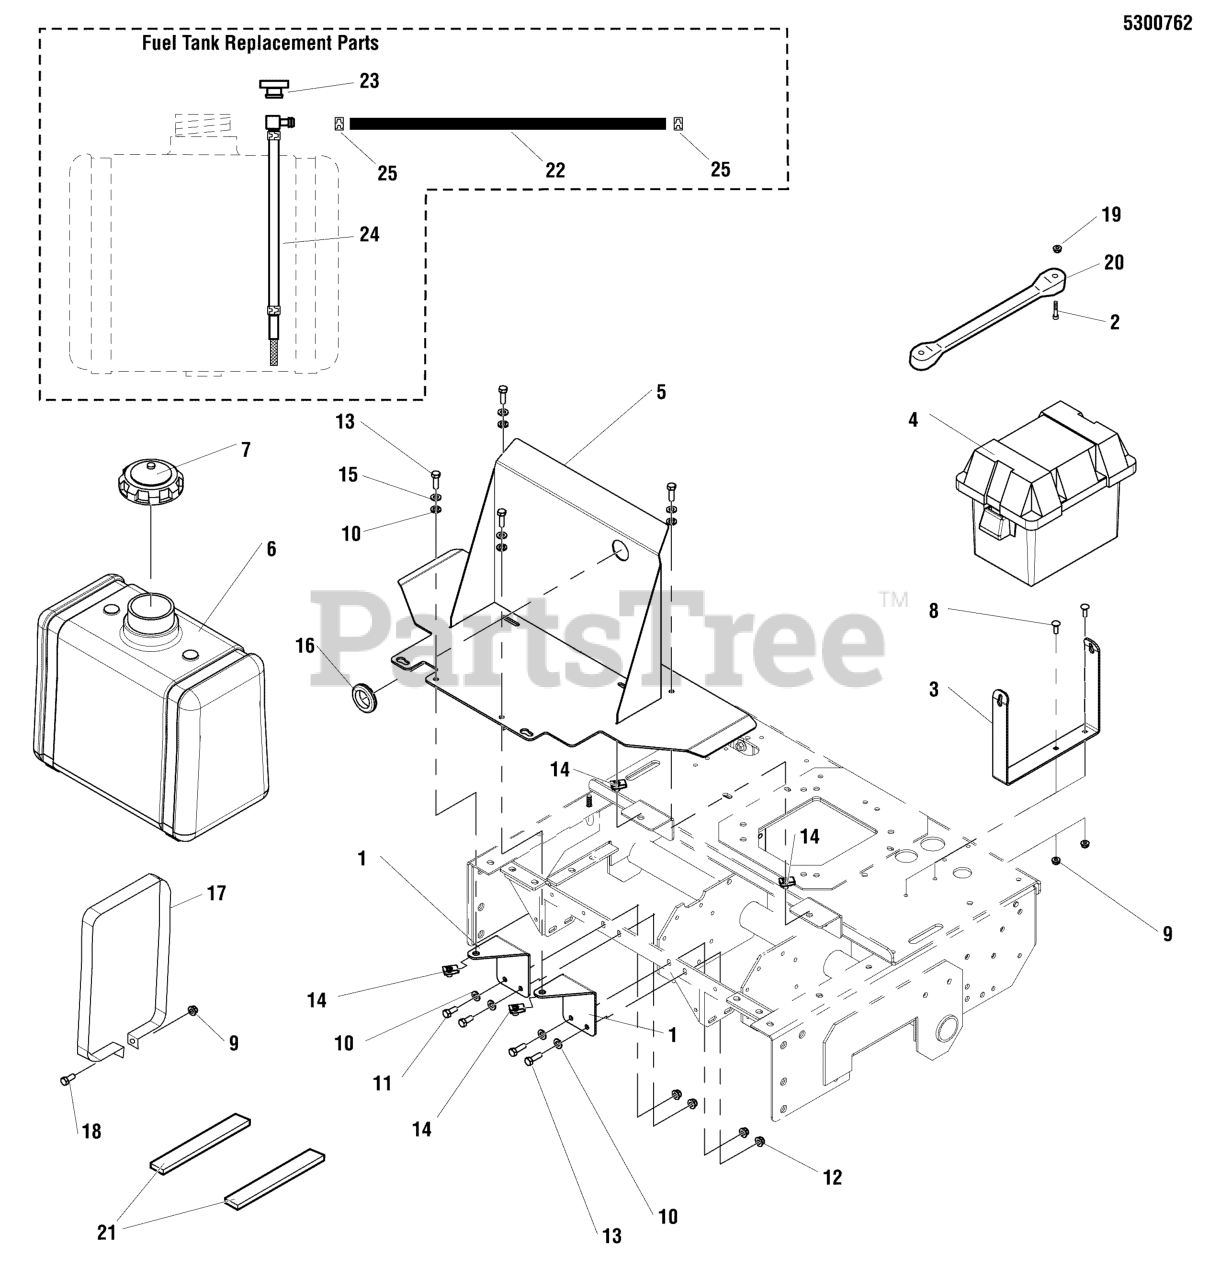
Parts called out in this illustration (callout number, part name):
1	MOUNT, GAS TANK, FRONT
2	SCREW, #10-24 X 1 RS, CZ
3	BRACKET, BATTERY BOX
4	BATTERY BOX, W/ DRAIN HOLE
5	WELD, TANK MOUNT
6	TANK, 5 GAL, W DROP TUBE/VENT
7	FUEL CAP, 3-1/2", MANAGED VENT OUT, 12"
8	BOLT,1/4-20X0.750,GR5,STD NECK,SQ,ZC/CL
9	NUT, 1/4-20 HEX NYLOCK FLANGE
10	WASHER, 5/16" SAE
11	BOLT, 5/16-18 X 3/4 GD5
12	NUT, 5/16-18 HEX NYLOCK FLANGE
13	BOLT, 5/16-18 X 1" GD5
14	BODY CLIP, 5/16-18-7GA MATERIAL
15	WASHER, 5/16 LOCK CZ
16	GROMMET, 1-1/4"
17	STRAP, FUEL TANK
18	BOLT, 1/4-20 X 1-1/2"
19	NUT, #10-24, HEX NYLON LOCK
20	STRAP, RUBBER
21	PAD, RUBBER MOUNT
22	HOSE, 1/4 FUEL, 25" LONG
23	GROMMET
24	FUEL LINE, TOP DRAW W/ SCREEN (SV)
25	CLAMP, HOSE, EXTERNAL, 1/2" RED
